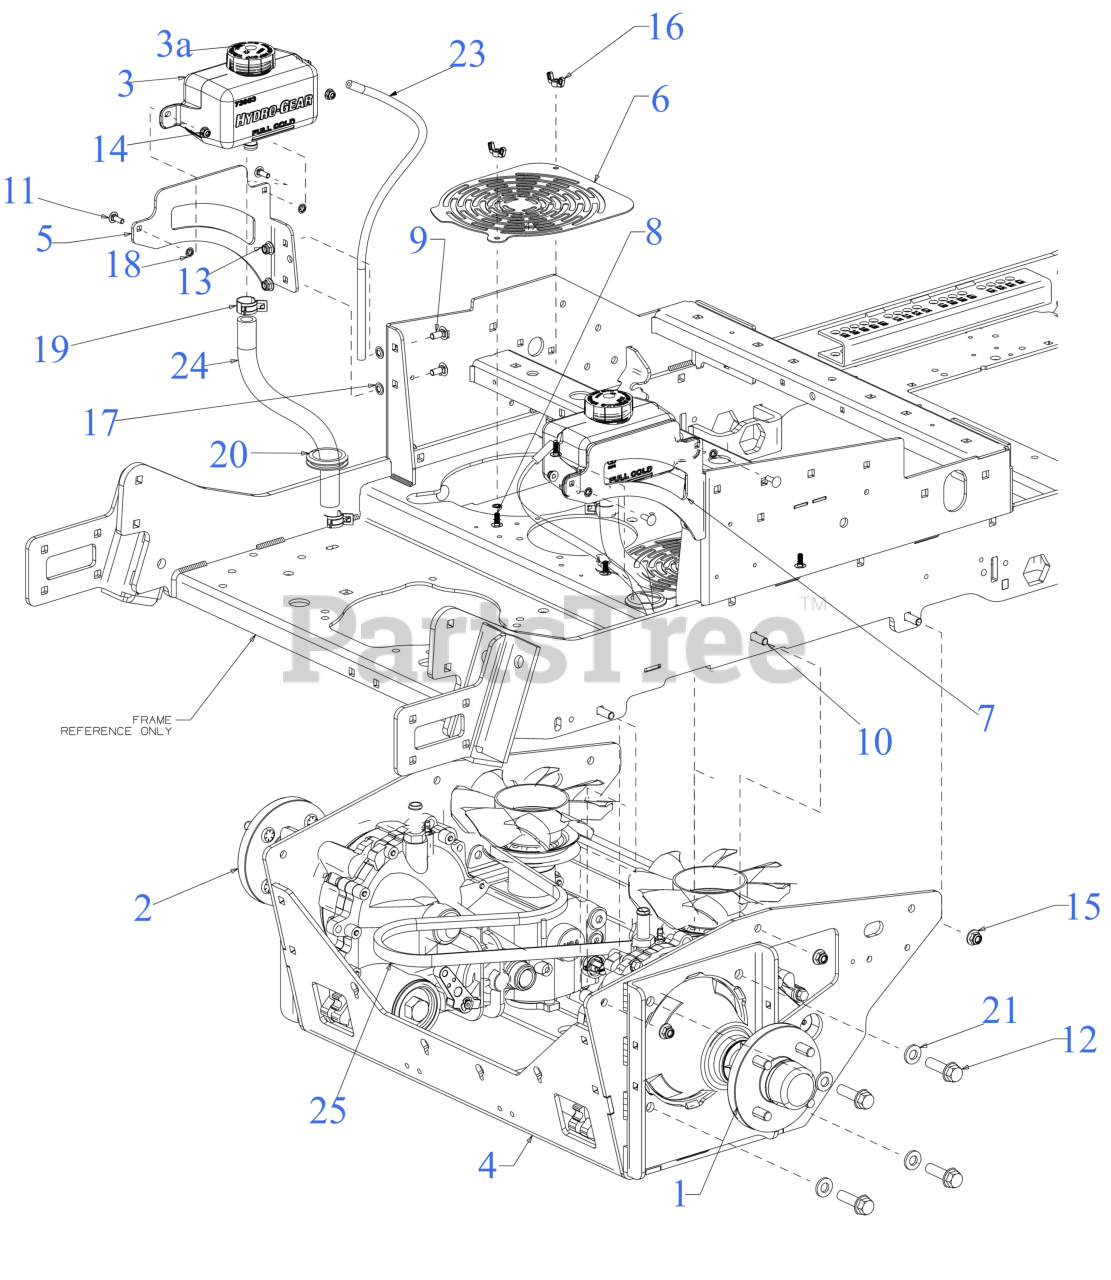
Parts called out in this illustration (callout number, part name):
1	HYDRO TRANSMISSION (RH) (W/RTN)
2	HYDRO TRANSMISSION (LH) (W/RTN)
3	1L EXPANSION TANK
4	SUB FRAME BRACKET
5	TANK MOUNT BRACKET (LH)
6	TRANSMISSION COVER PLATE
7	TANK MOUNT BRACKET (RH)
8	CARRIAGE BOLT 1/4-20 x .62
9	CARRIAGE BOLT 5/16-18 x .75
10	CARRIAGE BOLT 3/8-16 X1.25 GR5
11	SCREW 1/4-20 x .75 GR5
12	FLANGE BOLT 1/2-13:1.75:GR5
13	FLANGE LOCK NUT 5/16-18
14	FLANGE LOCK NUT
16	WING NUT 1/4-20
18	RETAINER-BOLT .25ID x .50OD
19	HOSE CLAMP
20	RUBBER GROMMET (1.50X2.13X.563)
21	FLAT WASHER .510 x 1.000 x .125
23	VENT HOSE 3/16 ID 45"LG
24	OIL HOSE 5/8 ID X 12.5 LG
25	V-BELT 66.34"
